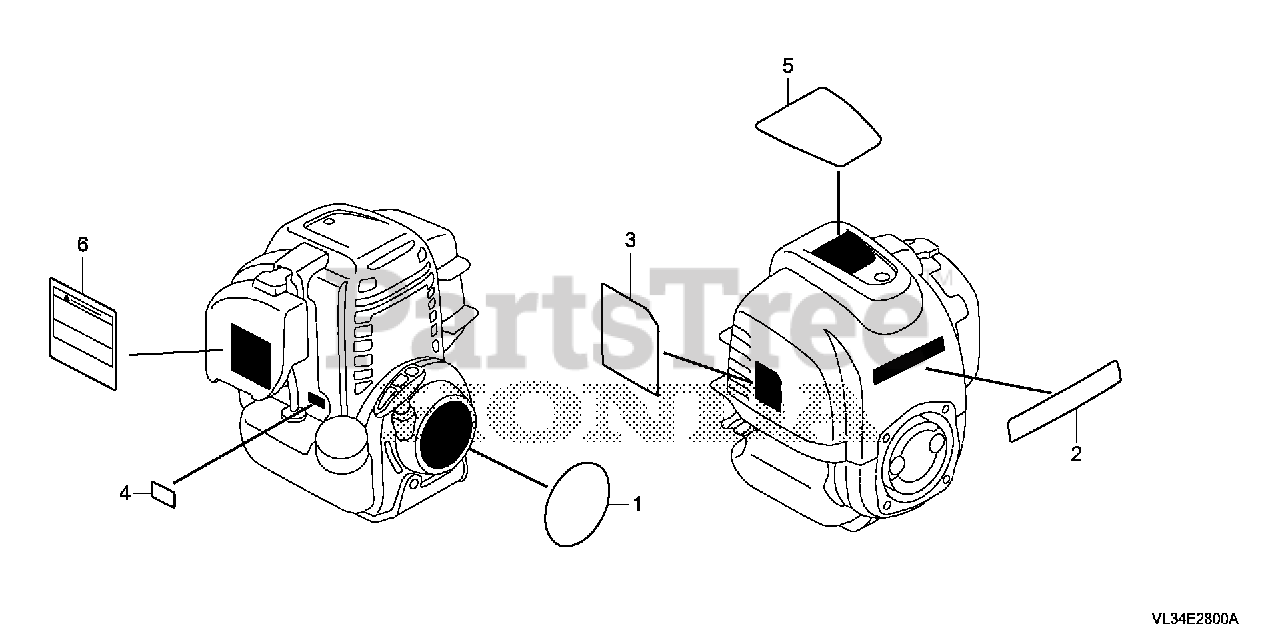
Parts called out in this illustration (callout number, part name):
1	MARK, EMBLEM
3	LABEL, SPARK WARNING
4	MARK, TYPE (GY5)
5	MARK (4-STROKE)
